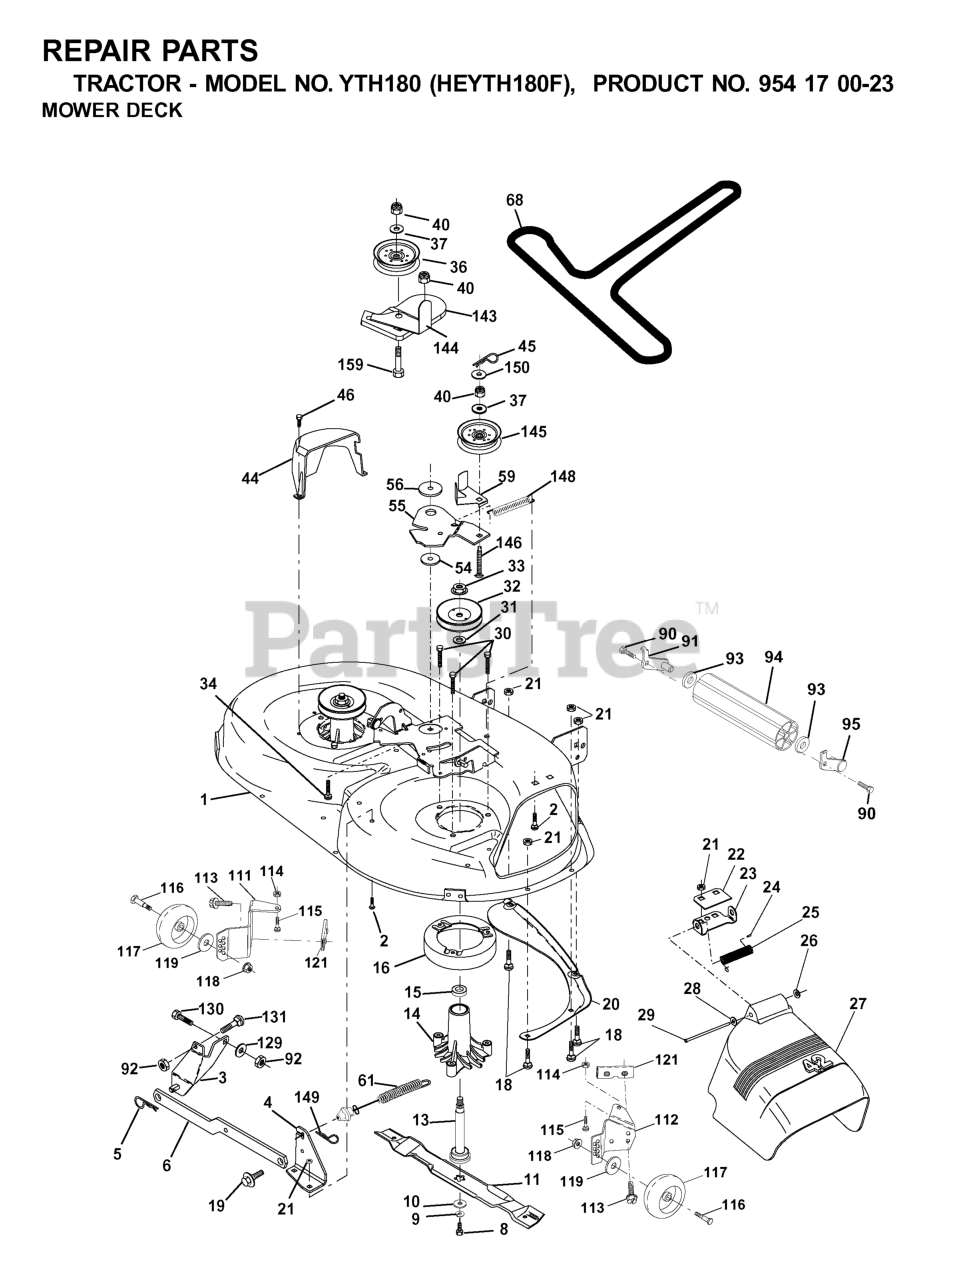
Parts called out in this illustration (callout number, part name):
1	42" DECK KIT
2	RP BOLT 5/16-18 X3/4 ZN/YEL GR
3	BRKT ASM SWAY BAR
4	BRACKET SWAY BAR 42" DECK
5	RETAINER-SPRNG RB
6	REAR SUSP ARM
8	BLADE BOLT
9	LOCKWASHER
10	WASHER.BLADE
11	Blade Mower 42" High Perf.
13	SHAFT ASM VENT
14	HOUSING.MANDREL.VENTED (MACHD)
16	STRIPPER.MANDREL.ROUND.BLACK
18	BOLT
19	BOLT SHD 5/16-18
20	BAFFLE.VORTEX
21	LOCKNUT
22	STIFFENER BRACKET
23	DEFLECTOR BRACKET
24	CAP-SLEEVE LT
25	SPRING TORSION
26	NUT PUSH M
27	SHIELD DEFLECTOR
28	Washer 11/32 x 5/8 x 16 Ga SD
29	ROD.HINGE
30	SCREW THDROL ROLLING WASHER HD
31	WASHER
32	PULLEY/MANDREL
33	NUT
36	FLAT IDLER PULLEY
37	WASHER
44	GUARD MANDREL LH BLACK
45	RETAINER M
46	SCREW.1/4-20X5/8
54	HARDENED WASHER
55	ARM IDLER 42" MOWER LT/YT
56	SPACER.RETAINER.MOWER
59	GUARD, BELT
61	SPRING EXT ELEC CLUTCH
68	V-BELT PRIMARY 42"
90	SCREW
91	BRACKET ASM, ROLLER (L)
93	Washer 1 17/32 X 7/8 X 16 Ga
94	NOSE ROLLER
95	BRACKET ASM, ROLLER
111	BRACKET WHEEL GAUGE LH 42" DK
112	BRACKET WHEEL GAUGE RH 42" DK
113	Screw Tapping 5/16-18 Unc
114	NUT
115	BOLT.CARR.5/16-18X1/2
116	BOLT M
117	WHEEL.GAUGE.STANDARD
118	LOCKNUT
119	WASHER.5/16.FLAT.STE.STD.
121	BRACKET.EXTRUDED.GAGE.WHEEL
129	WASHER
131	BOLT D
143	BRACKET, ARM IDLER
144	DNO KEEPER.BELT.42".CLUTCH.CBL
145	PULLEY
146	BOLT, CARRIAGE IDLER BLACK
148	IDLER RETURN SPRING
149	SPRING.RETAINER.YELLOW.ZINC
